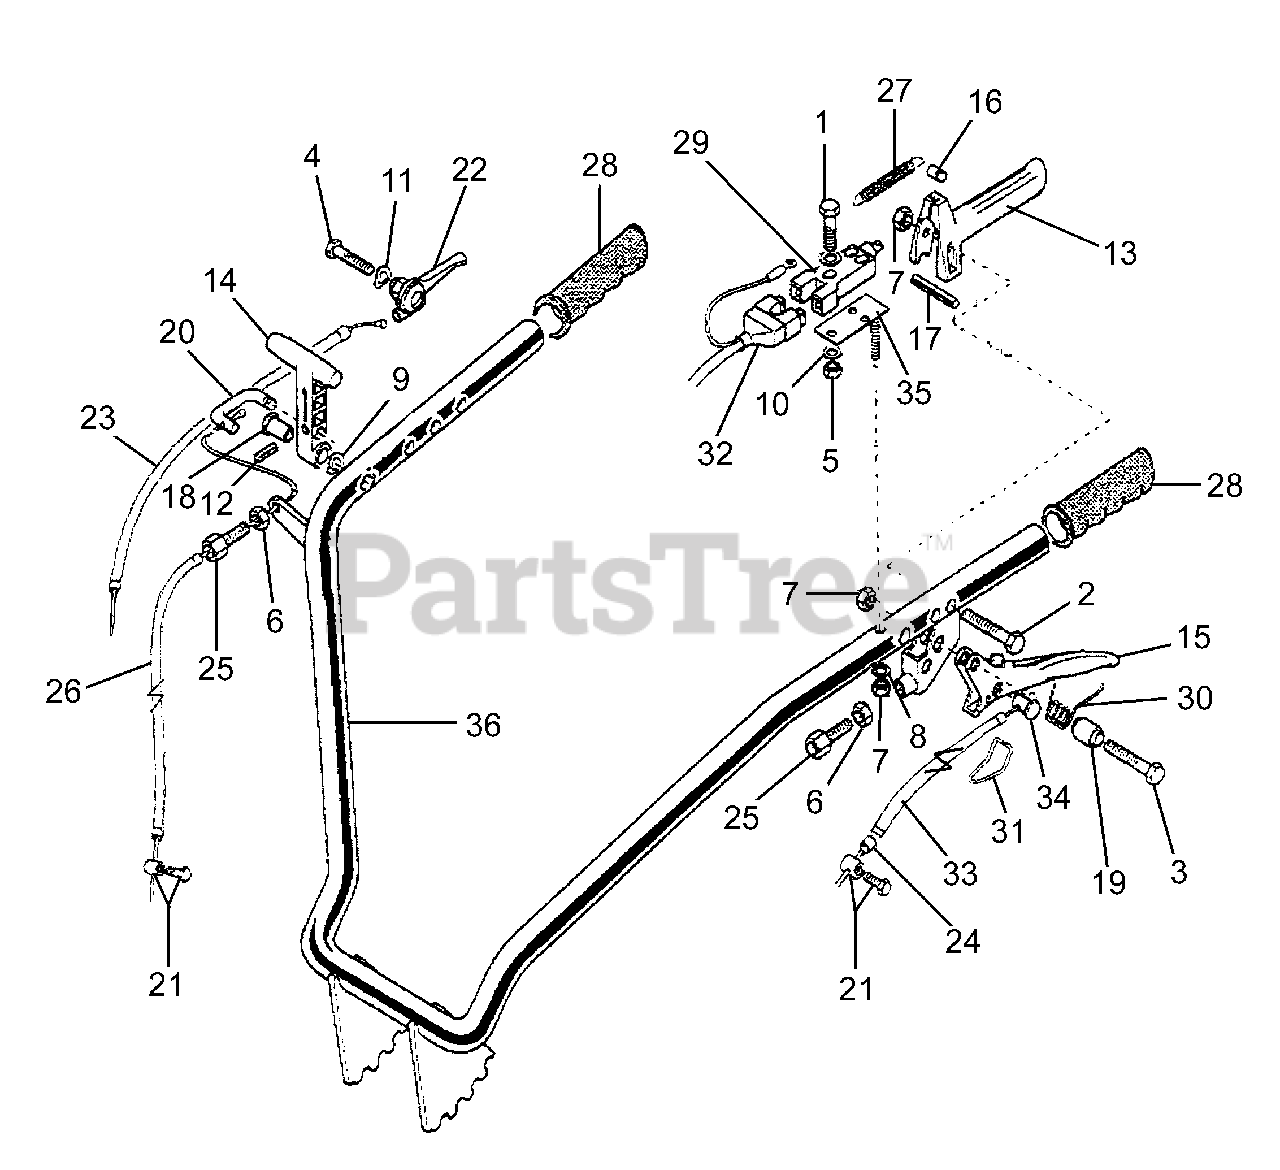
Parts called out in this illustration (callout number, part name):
1	HEX SCREW M4X25
2	HEX. SCREW M6X45 UNI 5737 8G
3	HEX. SCREW M6X25 UNI 5739-8G
4	HEX SCREW M8X35 UNI 5739-8G
5	NUT M4 UNI 5588-5S
6	NUT M8 UNI 5588-5S
7	LOCKNUT M 6
8	WASHER P.6,4X12,5 UNI 6592
9	WASHER P.8,4X17 UNI 6592
10	SPRING WASHER B 4.3
11	SPRING WASHER B 8.4 DIN 137
12	SPLIT PIN 4X20 SPIROL
13	LEVER MOTOR-STOP
14	REVERSER CONTROL LEVER
15	CLUTCH LEVER
16	M/S SPRING RETAINER PIN
17	PIN/MOTOR STOP LEVER
19	LEVER SPACER
21	TERMINAL SCREW M 5
22	GAS CONTROL LEVER
23	CABLE TO GAS SHEATH
25	ADJUSTING SCREW M 8
26	CLUTCH SHEATH & CABLE L 930
27	M/STOP SPRING COMPL.DIRECT
28	KNOB D=27 GLISSA
29	STOP SWITCH
30	SPRING FOR LEVER
32	M/STOP HARNESS MF
33	CABLE AND SHEATH L=800
35	STOP SWITCH SUPPORT COMPL.
36	MOTOR MOWER HANDLEBAR
